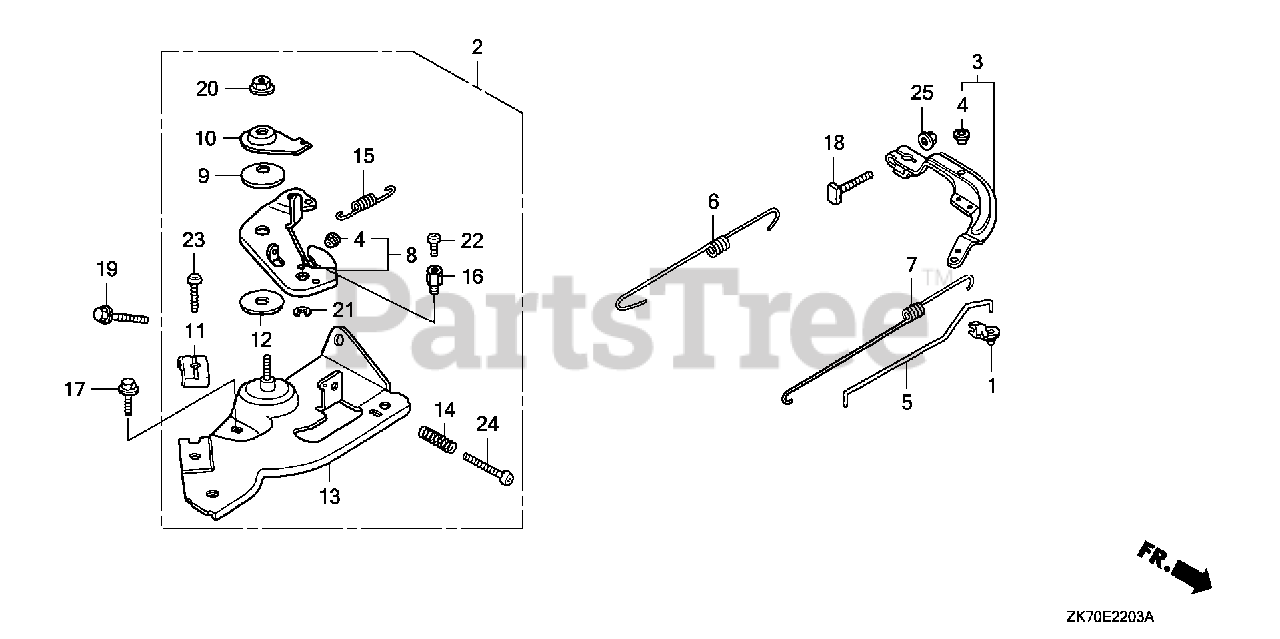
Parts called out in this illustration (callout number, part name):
1	JOINT, ROD
2	CONTROL ASSY.
3	ARM, GOVERNOR
4	COLLAR, LEVER
5	ROD, GOVERNOR
6	SPRING, GOVERNOR
7	SPRING, THROTTLE RETURN
8	LEVER, CONTROL
9	SPRING, LEVER
10	WASHER, CONTROL LEVER
11	HOLDER, CABLE
12	SPACER, CONTROL LEVER
13	BASE, CONTROL
14	SPRING, CONTROL ADJUSTING
15	SPRING, CABLE RETURN
16	HOLDER, WIRE
17	BOLT, FLANGE (6X12) (CT200)
18	BOLT, GOVERNOR ARM
19	BOLT, FLANGE (6X20) (CT200)
20	NUT, SELF-LOCK (6MM)
21	CIRCLIP (5MM)
22	SCREW, PAN (4X6)
23	SCREW, PAN (5X16)
24	SCREW, PAN (5X25)
25	NUT, FLANGE (6MM)
